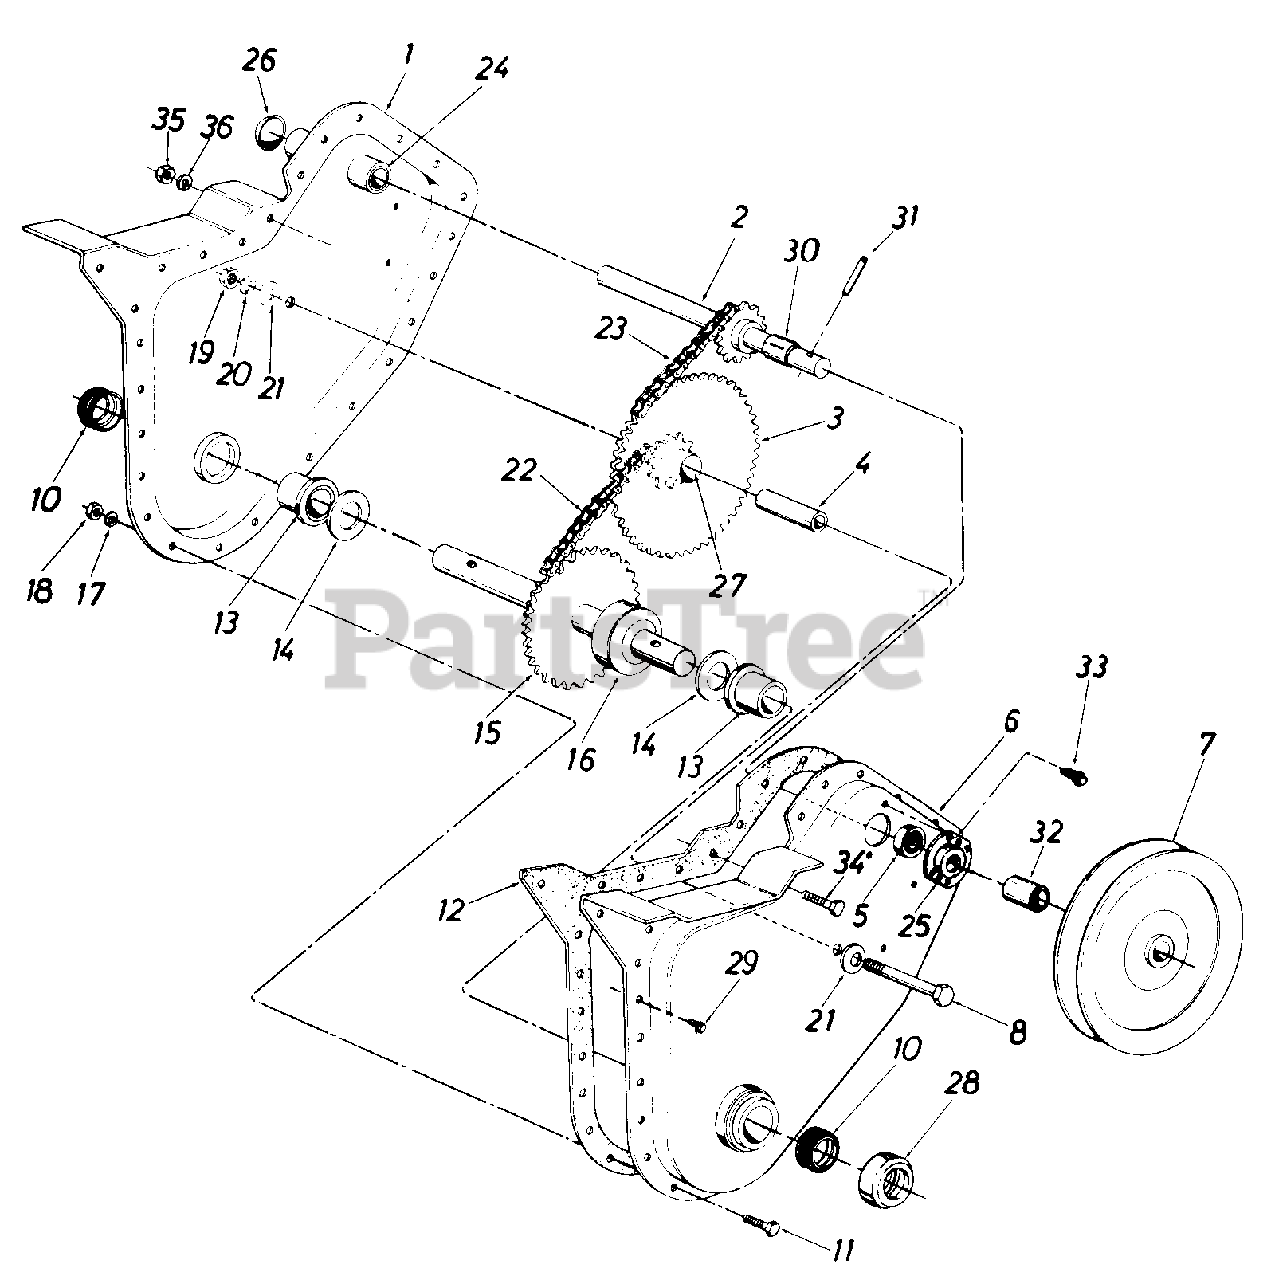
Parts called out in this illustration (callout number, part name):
1	HOUSING-CHAIN-CASE RH
2	SHAFT ASSY-INPUT
3	SPROCKET & HUB ASSY
4	BEARING-INNER RACE
5	BEARING-BALL
6	CHAIN CASE HSG-LH
8	SCREW-HEX 3/8-24 x 2.50
11	SCREW-HEX 1/4-28 x .62
12	GASKET
13	BEARING-FLANGE
14	WASHER-FL-.88 x 1.50 x .030
15	SHAFT ASSY-TINE
17	LOCK WASHER 1/4 DIA
18	NUT-HEX 1/4-28
19	NUT-HEX INS L-3/8-24
20	WASHER-LOCK-3/8
21	WASHER-BELL .3/8ID x 1.12OD x .030
22	#420 CHAIN 1/2 PITCH x 37 LINKS
23	#35 CHAIN 3/8 PITCH x 49 LINKS
25	HOUSING-BRG
26	PLUG-EXPANSION
27	BEARING-SLEEVE
29	SCREW-HEX WASH SF TAPP
31	PIN-SPRING SPIRAL 1/4 x 1.5 HEAVY DT
33	SCREW-TAP 1/4-20 x .38
34	SCREW-HEX 5/16-18 x .75
35	NUT-HEX 5/16-18
36	WASHER-LOCK-5/16
